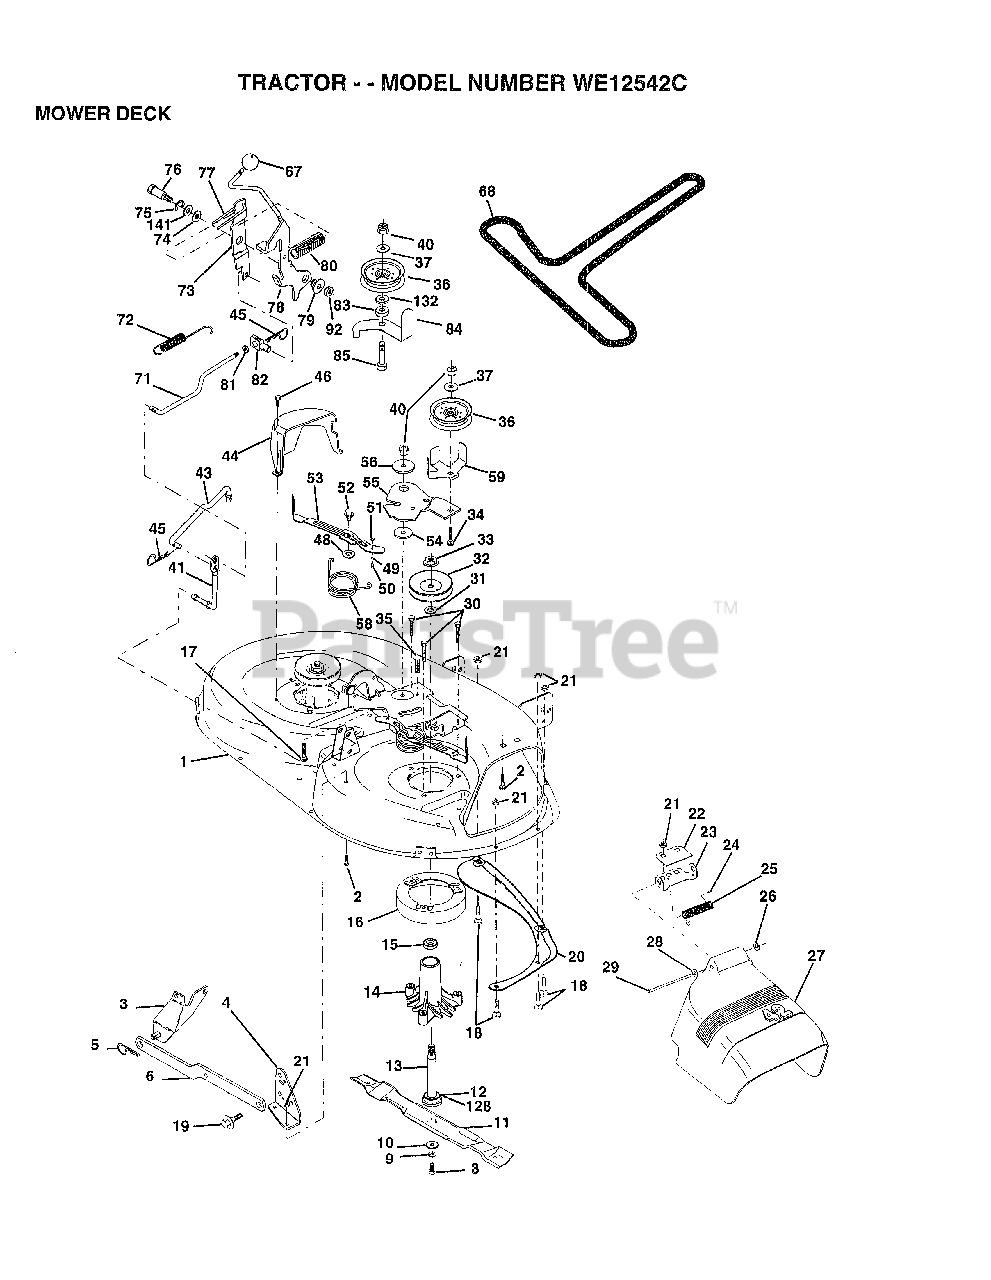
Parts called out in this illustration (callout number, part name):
1	DECK.WELD.42.
2	BOLT
3	BRKT ASM SWAY BAR
4	BRKT DECK SW BAR
8	BLADE BOLT
10	WASHER.HARD.BLADE
11	"BLADE.42"" HIPERF"
12	BEARING.BALL
14	HSG ASM MANDREL
15	BEARING
16	STRIPPER RND MWR
17	BOLT RDHD 3/8-16
18	BOLT
19	BOLT SHD 5/16-18
20	BAFFLE VORTEX 42
22	STIFFENER BRKT
23	DEFLECTOR BRKT
24	CAP-SLEEVE LT
25	SPRING TORSION
26	NUT PUSH M
27	DEFLECTOR.SHIELD
28	WASHER
29	HINGE ROD
30	"SCREW-THD ROLL,WA"
31	WASHER
32	PULLEY.MANDREL.42
34	BOLT
35	XMAS TREE FASTNER
36	FLAT IDLER PULLEY
37	WASHER
41	PIVOT ROD
43	ROD CLUTCH W/NIBS
44	GUARD MAND LH BLK
45	RETAINER M
46	SCREW.1/4-20X5/8
48	HARD SMALL WASHER
49	ROLLER ASM-CAM
50	SHOULDER BOLT
51	LOCKNUT
52	BOLT.SHLD.5/16-18
53	BRAKE PAD ARM ASM
54	HARDENED WASHER
55	ARM-IDLER
56	SPACER RETAINER
58	SPRING TORSN BRAK
59	GUARD IDLER TUV
67	KNOB.RD.7/16-14
68	BELT.V.T-PATH
71	ROD CLUTCH 38/42
72	RETURN SPRING
73	CLUTCH ARM SECOND
74	WASHER
75	RING
76	SHOULDER BOLT
77	SPRING KEEPER
78	LEVER.ASM.CLUTCH
79	BUSHING
80	SPRING.CLUTCH.MWR
81	NUT
82	TRUNION ADJ
83	WASHER
84	"KEEPER-BELT,FIXED"
85	BOLT
92	NUT
128	WASHER.FELT.
132	WASHER GT
141	WASHER .T
